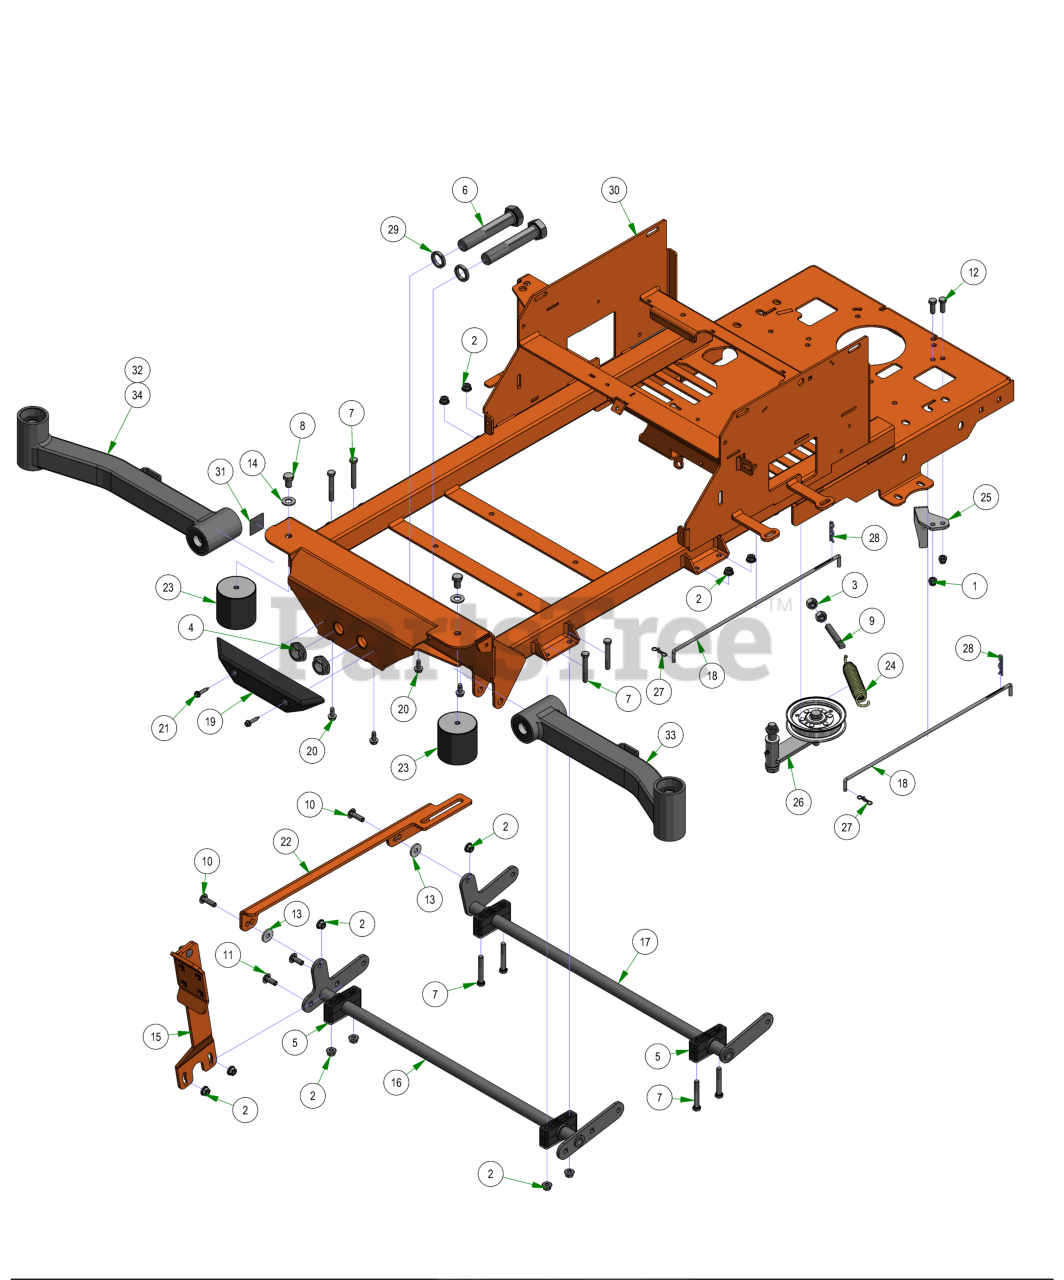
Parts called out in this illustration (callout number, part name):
1	3/8-16 NYLON INSERT LOCKNUT ZINC
2	3/8-16 NYLON INSERT FLANGE LOCKNUT (GR.F) ZINC
3	1/2-13 HEX NUT ZINC
4	1"-14 NYLON INSERT JAM LOCKNUT ZINC
5	Pillow Block Kit
6	1"-14 X 5-1/2 HEX CAP SCREW (GR.8) ZINC YELLOW
7	3/8-16 X 2-1/2 HEX CAP SCREW (GR.5) ZINC
8	1/2-13 X 3/4 HEX CAP SCREW (GR.5) ZINC
9	All Thread
10	3/8-16 X 1-1/4 CARRIAGE BOLT ZINC
11	3/8-16 X 1 CARRIAGE BOLT (GR.5) ZINC
12	3/8-16 X 1 GR 5 Hex Bolts Zinc
13	.390 ID X 1.12 OD X .125 THK FLAT WASHER NYLON
14	1/2 SAE FLAT WASHER (1-1/16" OD) GR.8 ZINC YELLOW
15	Foot Pedal Assembly
16	Actuator Bar Front- 2017 MZ/ZT
17	Actuator Bar Rear- 2017 MZ/ZT
18	Neutral Rod
19	Bumper EZT
20	5/16-18 X 3/4 HEX WASHER SLOT (F) TCS ZINC
21	1/4-14 X 1-1/4 HEX WASHER UNSLOT TEK/3 ZINC
22	2017 MZ/ZT Actuator Linkage
23	Vibration Mount- Red Dot
24	Deck Idler Spring
25	2025 ZT Clutch Bracket
26	ZT Pump Idler
28	Neutral Rod Clip
29	1.02 ID X 1.38 OD X .250 THK SPACER ZINC
30	2025 ZT Elite Frame
31	Independetly Articulating Front Suspension Arms Patent Decal
32	2021 ZT Suspension Arm Assembly Short Right (48")
33	2021 ZT Suspension Arm Assembly Left (48", 54", & 60")
34	2021 ZT Suspension Arm Assembly Long Right (54" & 60")
